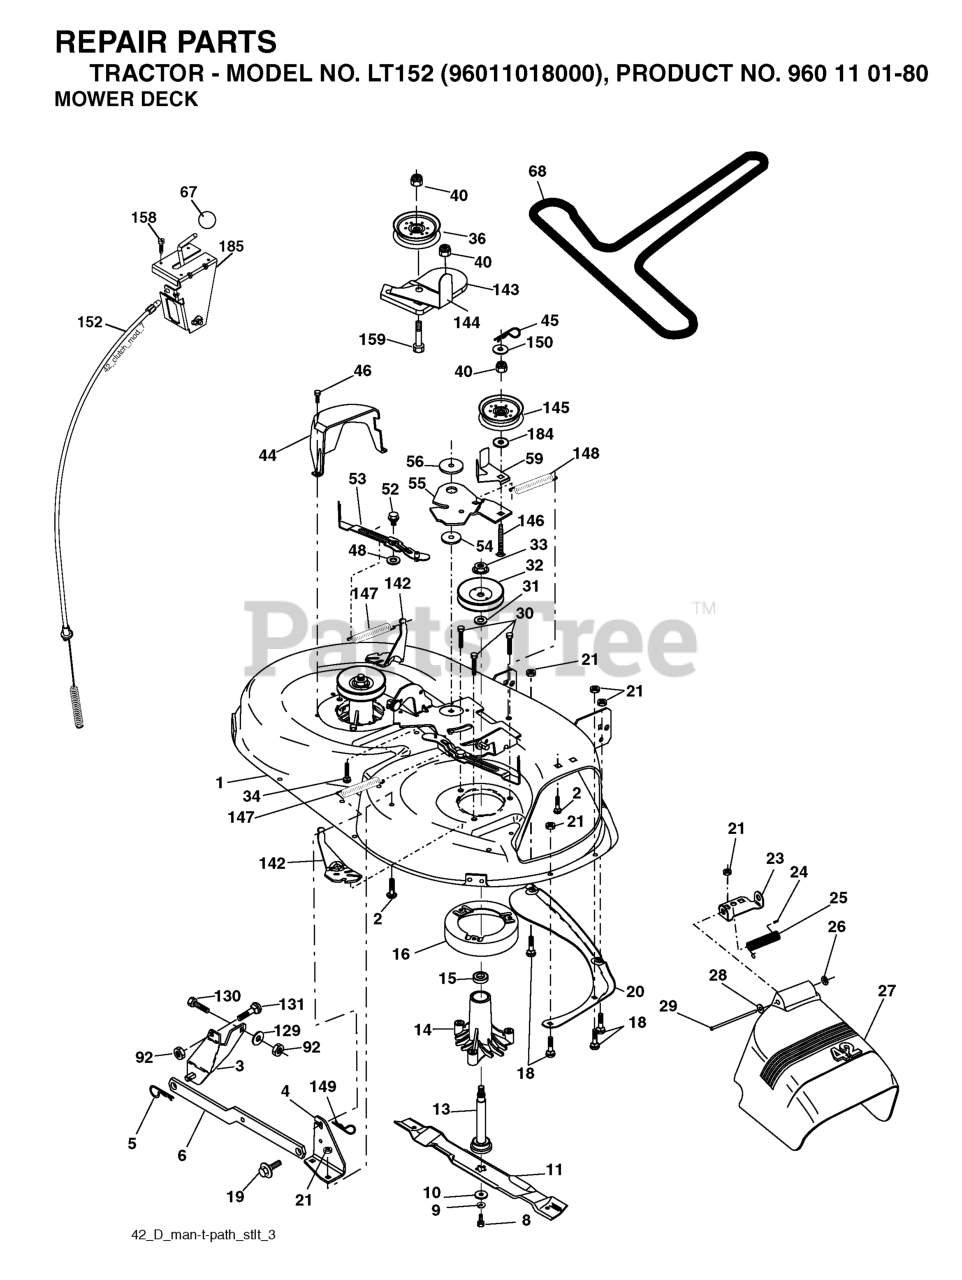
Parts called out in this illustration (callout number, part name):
1	42" DECK KIT
2	RP BOLT 5/16-18 X3/4 ZN/YEL GR
3	BRKT ASM SWAY BAR
4	BRACKET SWAY BAR 42" DECK
5	RETAINER-SPRNG RB
6	BAR SWAY DECK
8	BLADE BOLT
9	LOCKWASHER
10	WASHER.BLADE
11	42" HI-LIFT BLADE
13	SHAFT ASM VENT
14	HOUSING.MANDREL.VENTED (MACHD)
16	STRIPPER.MANDREL.ROUND.BLACK
18	BOLT
19	BOLT SHD 5/16-18
20	BAFFLE.VORTEX
21	LOCKNUT
23	BRKT, DEFL. MOWER
24	CAP-SLEEVE LT
25	SPRING TORSION
26	NUT PUSH M
27	SHIELD DEFLECTOR
28	Washer 11/32 x 5/8 x 16 Ga SD
29	ROD.HINGE
30	SCREW, WASHER HEAD
31	WASHER.SPACER.MANDREL
32	PULLEY/MANDREL
33	NUT.FLANGE.LOCK.TOP
34	BOLT.3/8-16X1.50
36	FLAT IDLER PULLEY
40	NUT LOCK FLG 3/8-16 UNC
44	GUARD MANDREL LH BLACK
45	RETAINER M
46	SCREW.1/4-20X5/8
52	BOLT.SHOULDER.5/16-18
53	ARM BRAKE ASSY
55	ARM IDLER 42" MOWER LT/YT
56	SPACER.RETAINER.MOWER
59	GUARD, BELT
67	KNOB T (3/8 HOLE)
92	NUT
111	BRACKET, WHEEL
112	BRACKET, WHEEL
113	BOLT.5/16HEX.WHS.HD
116	BOLT M
117	WHEEL.GAGE.HALF.SPOKED
118	LOCKNUT
119	WASHER.5/16.FLAT.STE.STD.
129	WASHER
131	BOLT D
142	ARM SPRING BRAKE MOWER
143	BRACKET, ARM IDLER
144	DNO KEEPER.BELT.42".CLUTCH.CBL
145	PULLEY
146	BOLT, CARRIAGE IDLER BLACK
148	IDLER RETURN SPRING
149	SPRING.RETAINER.YELLOW.ZINC
152	CABLE.CLUTCH.42"
158	SCREW
184	WASHER
185	HEAD ASM. CABLE CLUTCH
